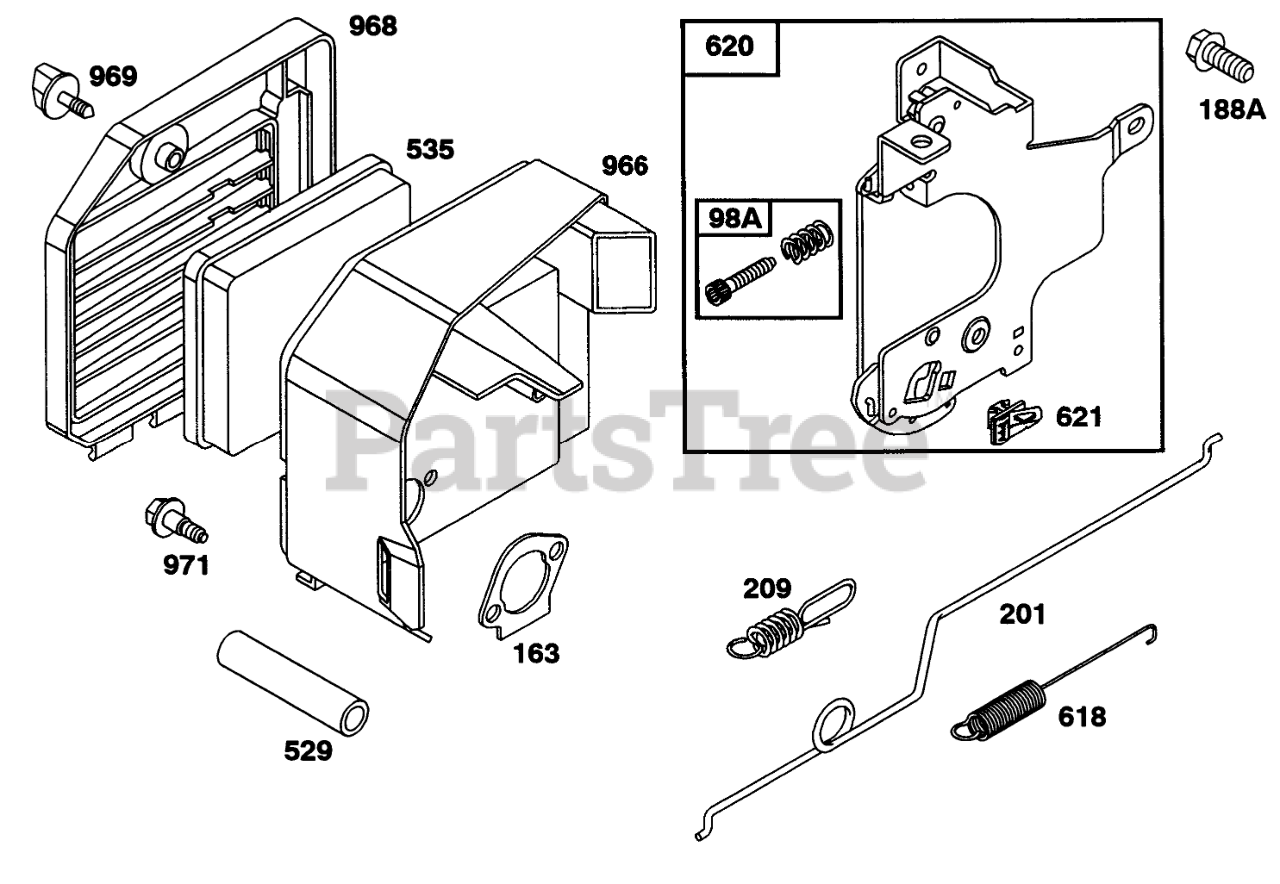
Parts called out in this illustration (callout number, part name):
98A	SPEED ADJUST. SCREW ASM
163	AIR CLEANER GASKET
188A	Screw-Hex Head
201	GOVERNOR LINK
209	GOVERNOR SPRING
529	BREATHER TUBE
535	FILTER ELEMENT
618	RETURN SPRING
620	CARBURETOR BRACKET
621	STOP SWITCH
966	AIR CLEANER BASE
968	AIR CLEANER COVER
969	AIR CLEANER SCREW
971	AIR CLEANER SCREW
977	CARBURATOR GASKET SET
